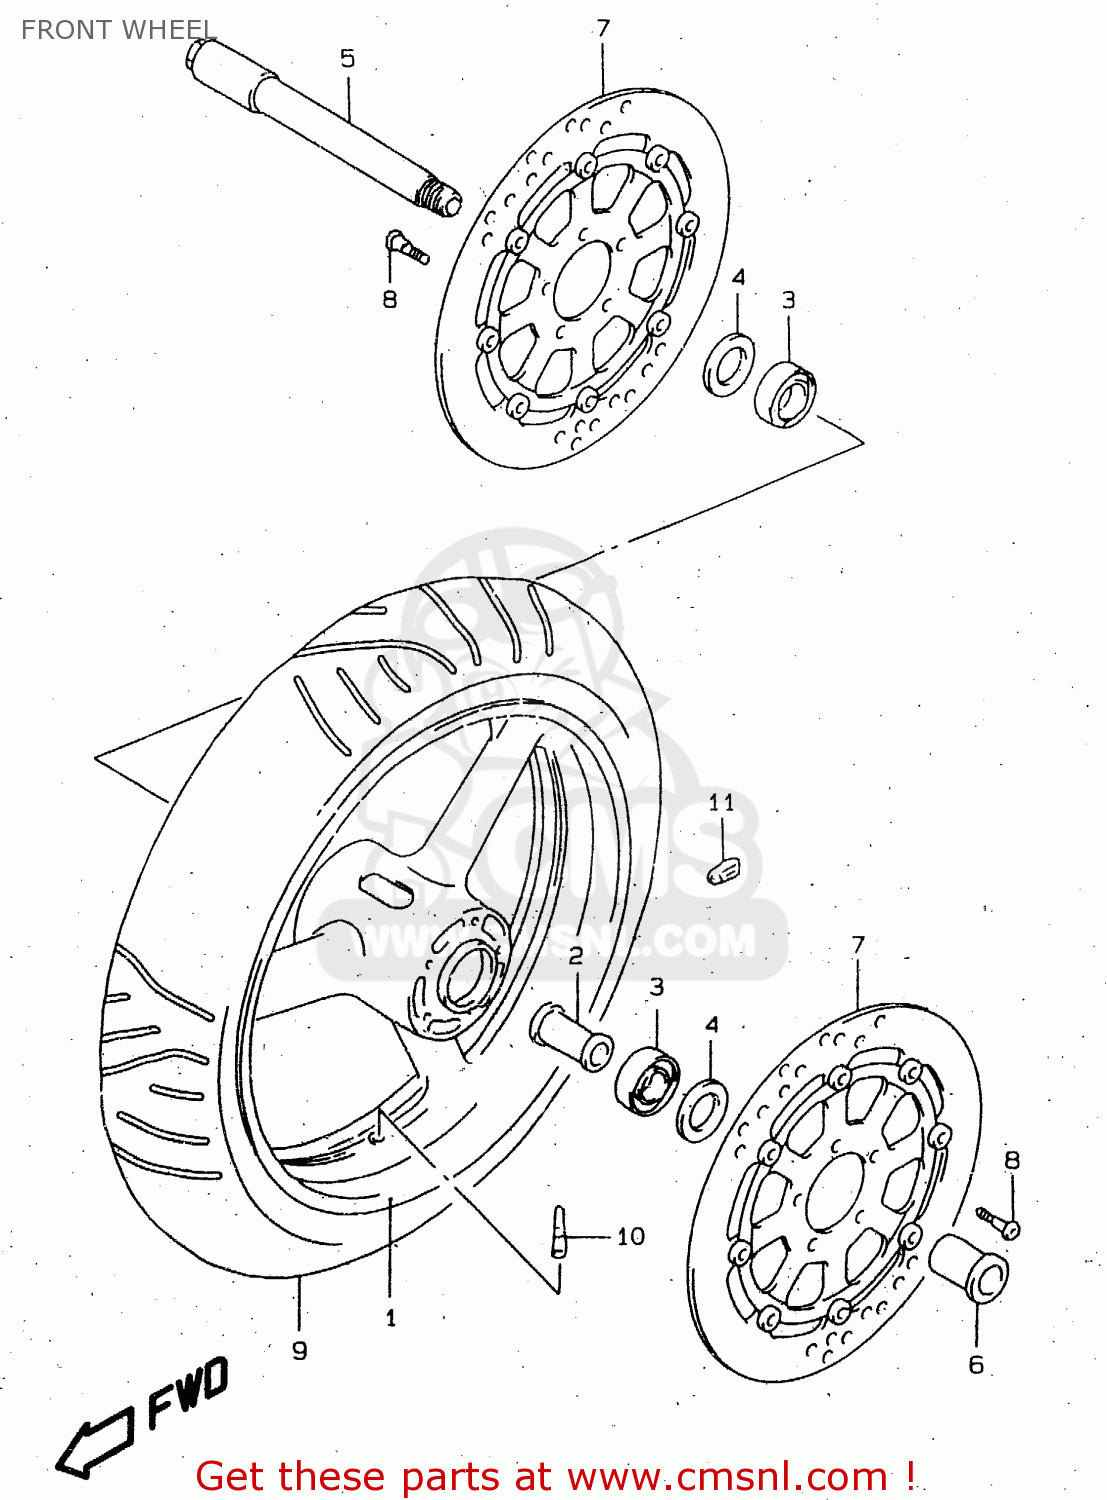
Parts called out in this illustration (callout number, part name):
1	WHEEL,FRONT (17XMT3.50)(
2	SPACER,FR HUB BEARING
3	BEARING(25X52X15)
4	SEAL,OIL(32X52X7)
5	AXLE,FR
6	NUT,FR AXLE
7	DISC,FR BRAKE
8	BOLT 8X33
9	TIRE 120/70 ZR17 (58W),M
10	VALVE ASSY,WHEEL RIM(TR412)
11	BALANCER,WHEEL (10G)
